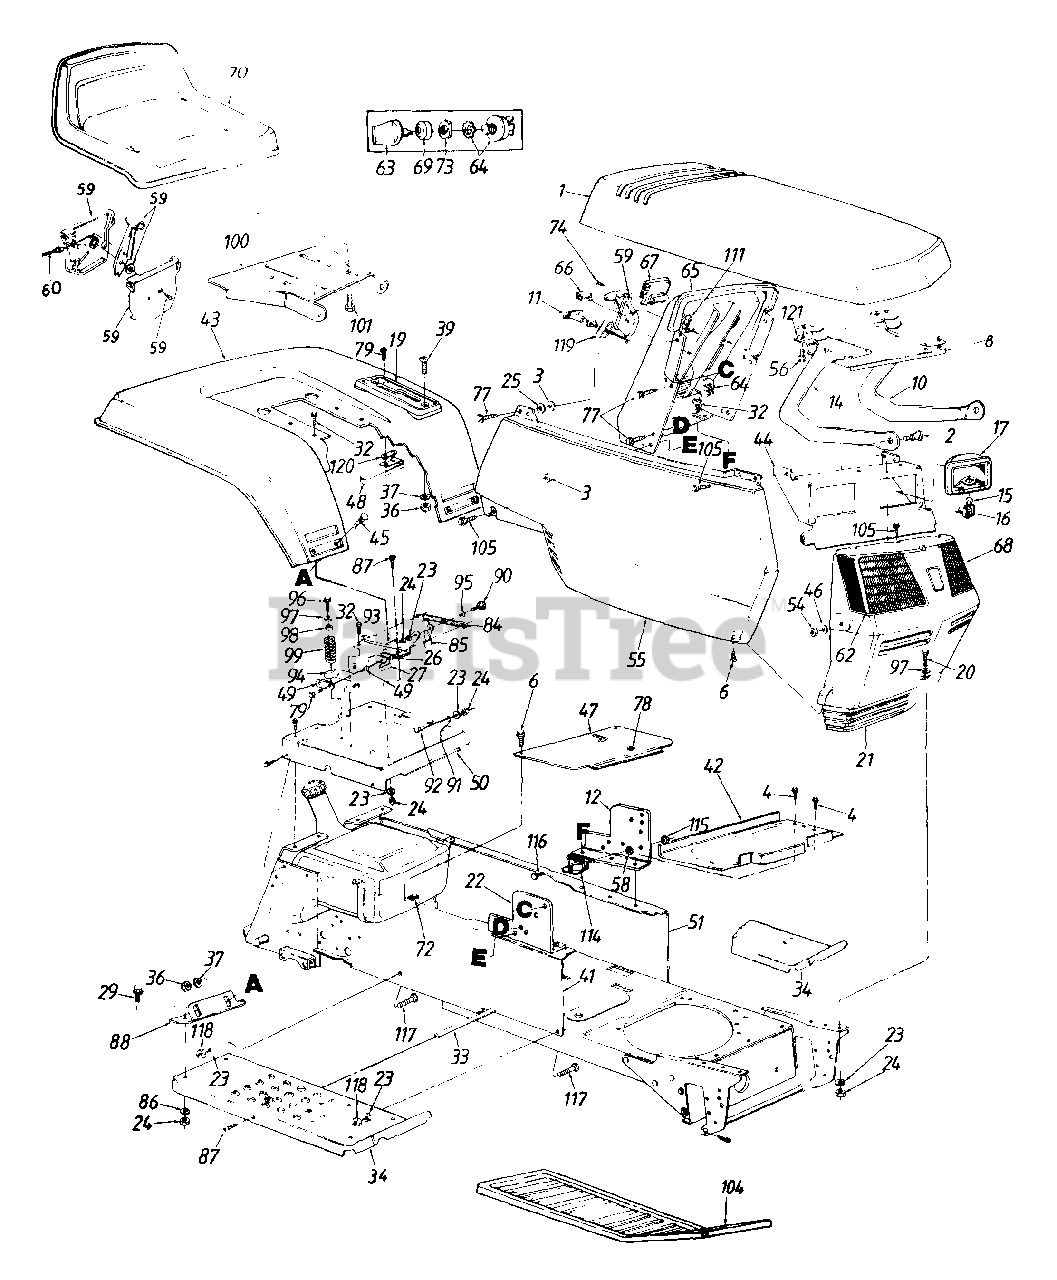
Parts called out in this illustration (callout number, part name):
2	Shld. Bolt .437" Dia. x .35"
3	Bolt Retainer 1/4" I.D.
4	Hex AB-Tap Scr. 1/4 x .62" Lg.
6	Truss Mach. B-Tap Scr. #10 x .5" Lg.
8	Hood Reinforcement
10	Hood Hinge - L.H.
11	Choke Control
12	Dash Support Brkt. - L.H.
14	Hood Hinge - R.H.
15	Lamp
16	Twist Lock - Lamp Socket
17	Headlight Housing
19	Speed Control Index Brkt.
20	Hex Bolt 5/16-18 x .75" Lg.
21	Grille
22	Dash Support Bracket - R.H.
23	L-Wash. 5/16" I.D.
24	Hex Nut 5/16-18 Thd.
25	Fl-Wash. 1/4" I.D. x .93" O.D.
26	Insulator Boss Plate
27	Seat Spring Switch
29	Hex Bolt 5/16-18 x 1.0" Lg.
32	Hex Wash. Hd. AB-Tap Scr. 5/16 x .75" Lg.
33	Running Board Rod
37	L-Wash. 1/4" I.D.
39	Truss Mach. Scr. 1/4-20 x 1.0" Lg.
41	R.H. Side Frame
42	Battery Plate
46	FL-Wash..328" I.0. x .68" O.D.
49	Insulator Plate
54	Hex Cent. I -Nut 5/16-18 Thd.
55	Side Panel Ass'y. - R.H.
56	Hex Wash. Hd. 8-Tap Scr. 1/4 x .62" Lg.
58	Ext L-Wash. 1/4" I D.
59	Throttle Control Box Ass'y.
60	Throttle Control Wire 35" Lg.
62	Lens - R H
63	Ignition Key
64	Ignition Switch
65	Dash Panel
66	Light Switch
67	Ammeter
68	Lens - L H
69	Ignition Switch Cap
70	Seat Ass'y
72	Speed Nut #10Z
73	Ignition Switch Nut
74	Truss Mach. AB-Tap Scr #10 x 5" Lg.
77	Hex Wash. Hd. Tap Scr 1/4 x 75" Lg.
78	Snap Bushing
79	Hex Wash. Hd. AB-Tap Scr #8 x 50" Lg.
84	Ext. Spring 5.31" Lg.
85	Seat Lift Brkt.
86	Bell-Wash. .345" I.D. x 88" O.D
87	Truss Machine Scr 5/16-18 x 75" Lg.
95	Spr.-Wash. .445" I.D.
96	Hex Wash. Hd. Tap Scr. 5/16-18 x .75" Lg.
97	Fl-Wash. .344" I.D, x 1" O.D.
98	Bushing
99	Compression Spring
100	Seat Pivot Bracket
101	Hex Tap Scr 3/8-16 x .75"
104	Foot Pad
105	Hex Tap Scr. 1/4-20 x .5" Lg.
111	Speed Nut 1/4-20 Thd.
114	Solenoid
115	Hex Sems Nut 1/4-20 Thd
116	Hex Bolt 1/4-20 x 5" Lg.
117	Rib Neck Bolt 5/16-24 x 75" Lg.
118	Hex Nut 5/16-24 Thd.
119	Retainer Clip
120	Insulator Nut Plate
